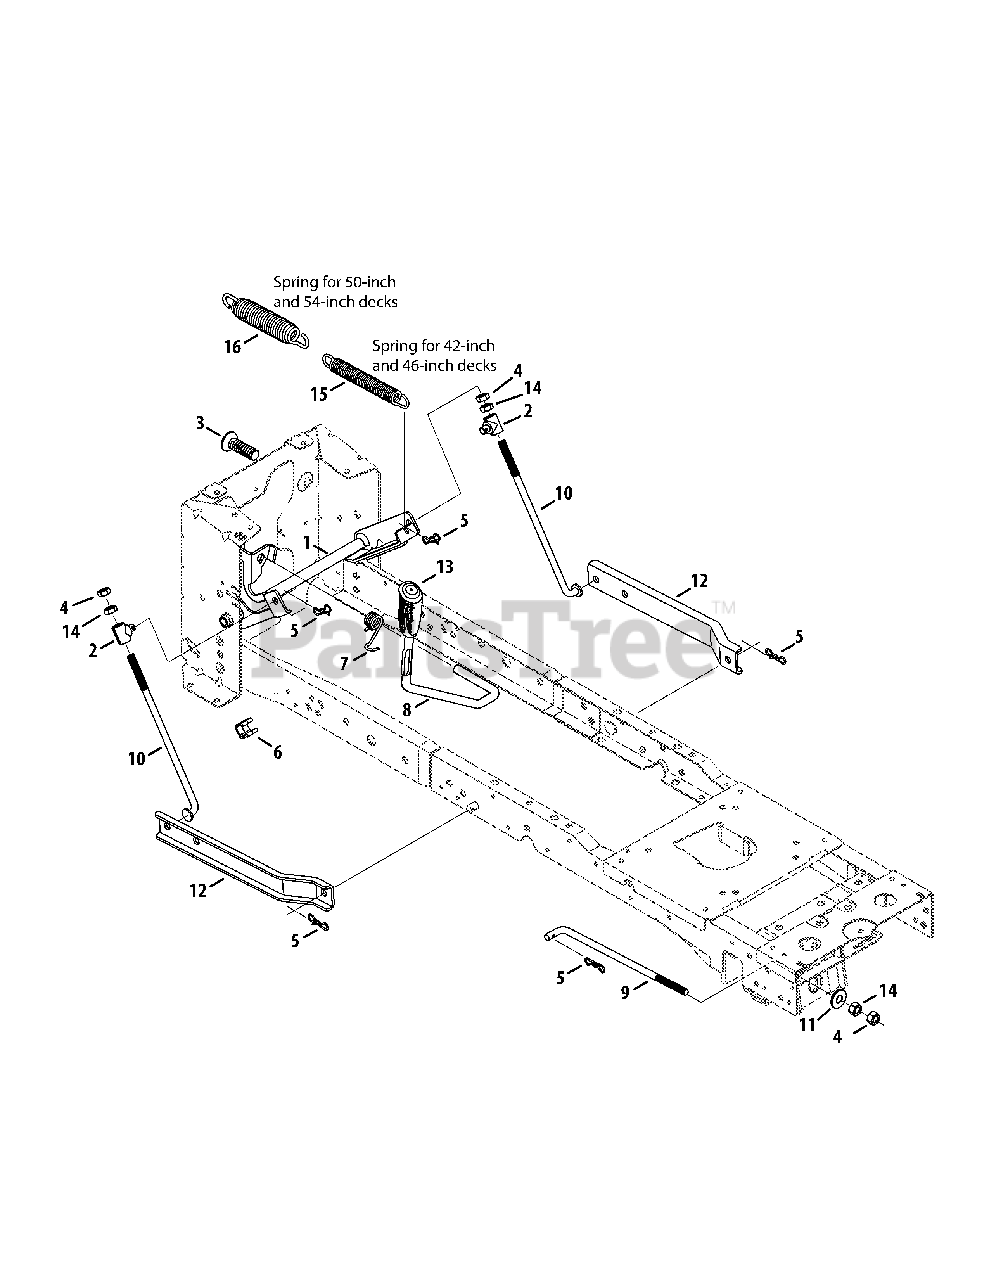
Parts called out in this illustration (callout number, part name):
1	Shaft Assembly, Lift
2	Ferrule, .510 x .496
3	Spring Insert
4	Nut, Jam, 1/2-13
5	Bow-Tie Cotter Pin
6	Spacer, .76 ID x .93 LG
7	Torsion Spring
8	Deck Lift Handle
9	Deck Lift Rod
10	Lift Adjustment Link
11	Pivot Cup
14	Hex Lock Nut, 1/2-13
15	Lift Assist Spring, (46")
16	Lift Assist Spring, (54")
